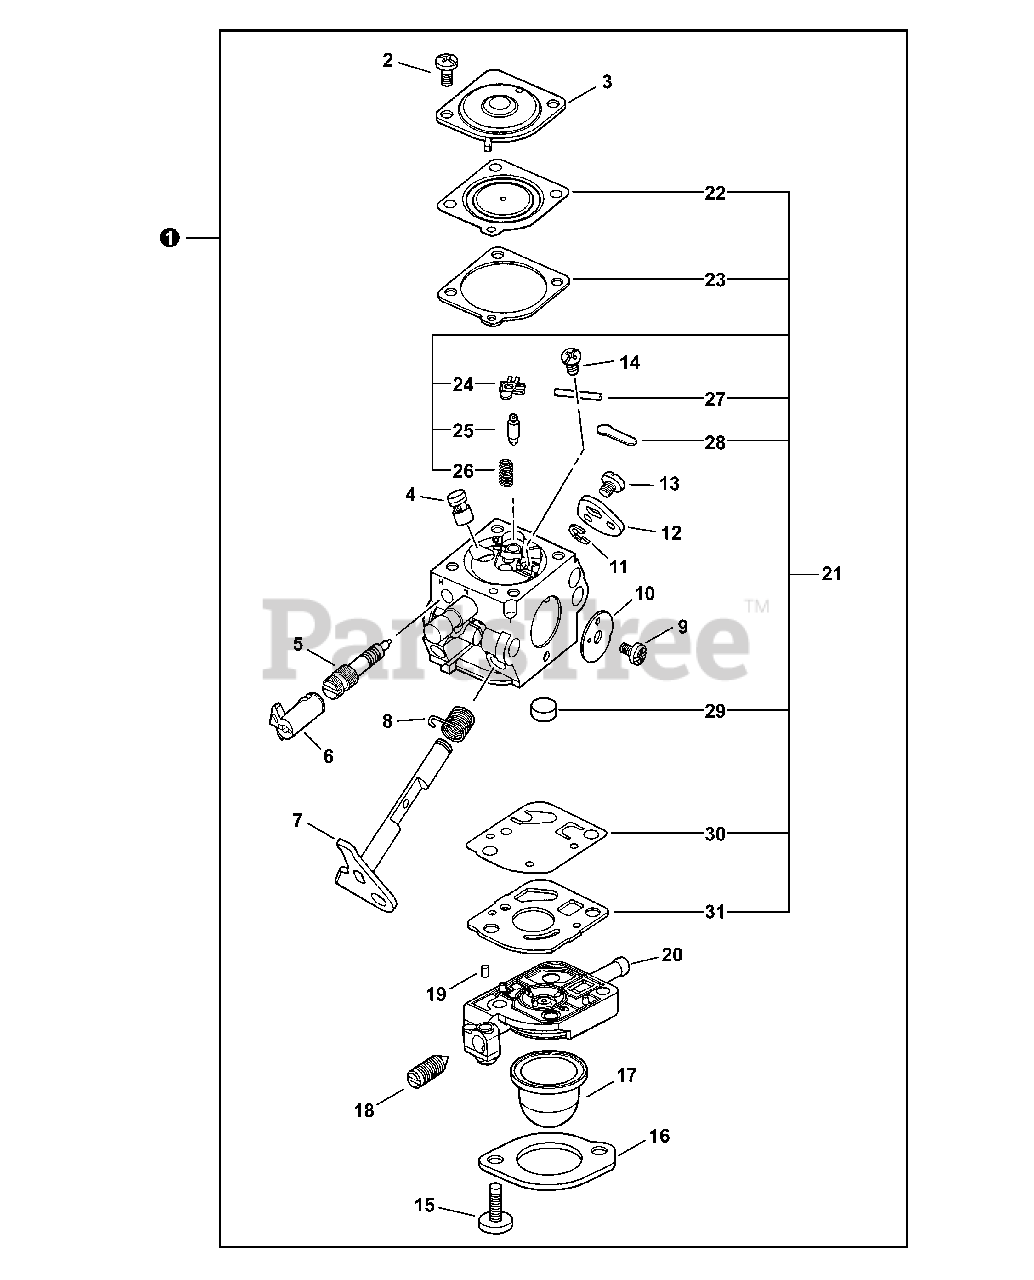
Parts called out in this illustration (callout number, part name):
1	CARBURETOR - C1U-K78
3	COVER, METERING DIAPHRAGM
4	NOZZLE, CHECK VALVE
5	NEEDLE, HIGH SPEED
6	CAP, LIMITER
7	SHAFT, THROTTLE
8	SPRING, THROTTLE RETURN
10	VALVE, THROTTLE
12	LEVER, THROTTLE
16	RETAINER
17	BULB, PURGE
19	PIECE, FRICTION
20	BODY ASSY, PURGE
21	REPAIR KIT, CARBURETOR
22	DIAPHRAGM, METERING
23	GASKET, METERING DIAPHRAGM
24	LEVER, METERING
25	VALVE, INLET NEEDLE
26	SPRING, METERING LEVER
27	PIN, METERING LEVER
28	PLUG, WELCH
29	SCREEN, FUEL INLET
30	DIAPHRAGM, PUMP
31	GASKET, PUMP
